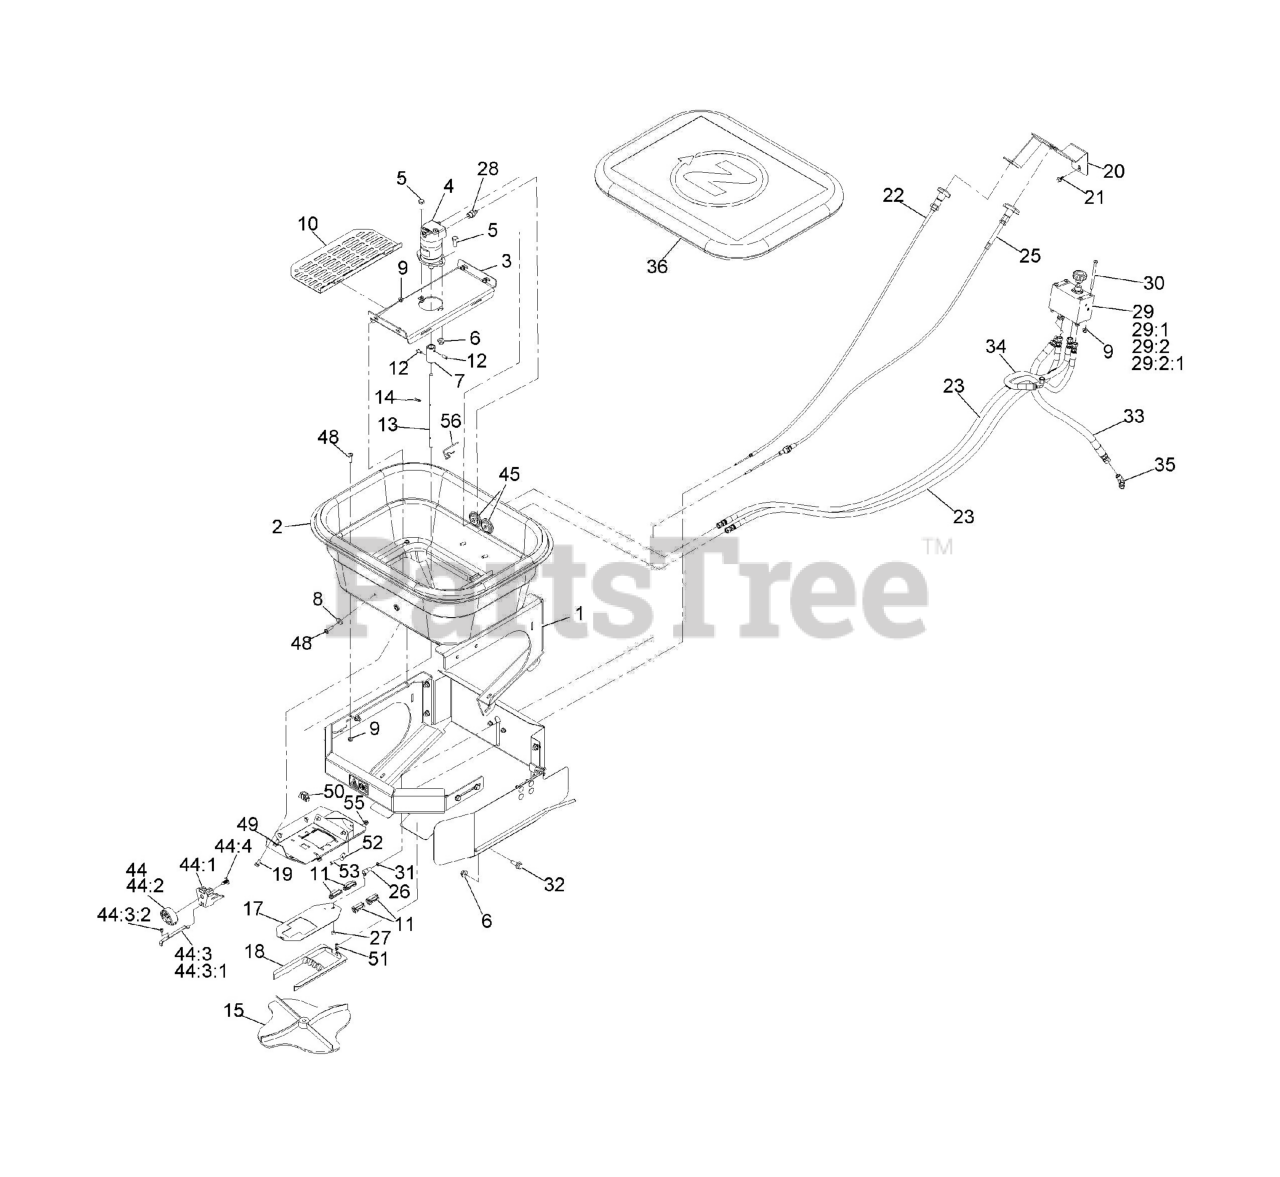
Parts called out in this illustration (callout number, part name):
1	Hopper ASM
2	HOPPER-120LB
3	PAN, HOPPER, 120
4	MOTOR-HYDRAULIC, SPREADER
5	SCREW-HH
6	Nut-Hex Flange
7	COUPLER-SS
9	Nut-Hex Flange
10	SCREEN, HOPPER, 120
11	GUIDE-RATE, GATE
12	Screw-SQH
13	SHAFT-HOPPER, 120
14	WIRE-AGITATOR
15	Spinner-Spreader
17	SLIDE-DOOR, HOPPER
18	DIFFUSER
19	SCREW-HHF
20	Bracket-Hopper Cable
21	Screw-HHF 1/4-20 X 5/8
22	CABLE-PUSH/PULL
23	HOSE ASM-HYD HP
25	CABLE-PUSH/PULL
26	BALL JOINT-SS
27	Nut,NYL Lock,#10-32,ST/ST 18-8
29	Manifold-Flow Control, Hopper
29:2	FITTING-ELBOW, 45 DEG
29:2:1	O-RING
30	Screw-HSBH
31	Nut,Hex Jam Mch Scr,10-32,Sst
32	SCREW-HHF
33	HOSE ASM-HYD HP
34	HOSE ASM
35	FITTING-90 SWIVEL
36	COVER-HOPPER, SMALL
44	RATE DIAL ASM
44:1	MOUNT-DIAL
44:3	Rate Gate Link ASM
44:3:1	LINK-GATE, RATE
44:3:2	SCREW-SHOULDER, SLOTTED
44:4	Footpad Fastener
45	Grommet-Hopper
48	Screw-Hsbhf
49	BASE PLATE, HOPPER, 120
50	HOPPER BOTTOM BEARING
51	WIRE-STOP
52	RETAINER, CABLE
53	SCREW-HH
55	Nut-Hex Flange
56	Clip-Spinner
